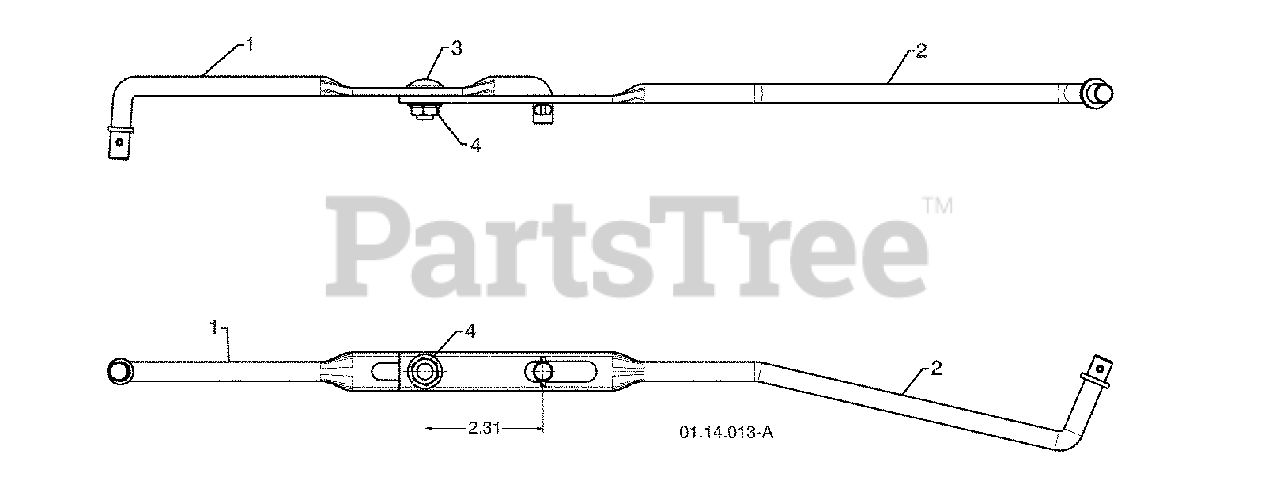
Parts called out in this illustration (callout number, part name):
1	SHIFTER ROD TOP
2	SHIFTER ROD BOTTOM
3	CARRIAGE BOLT 5/16-18 X .75
4	NUT 5/16-18
